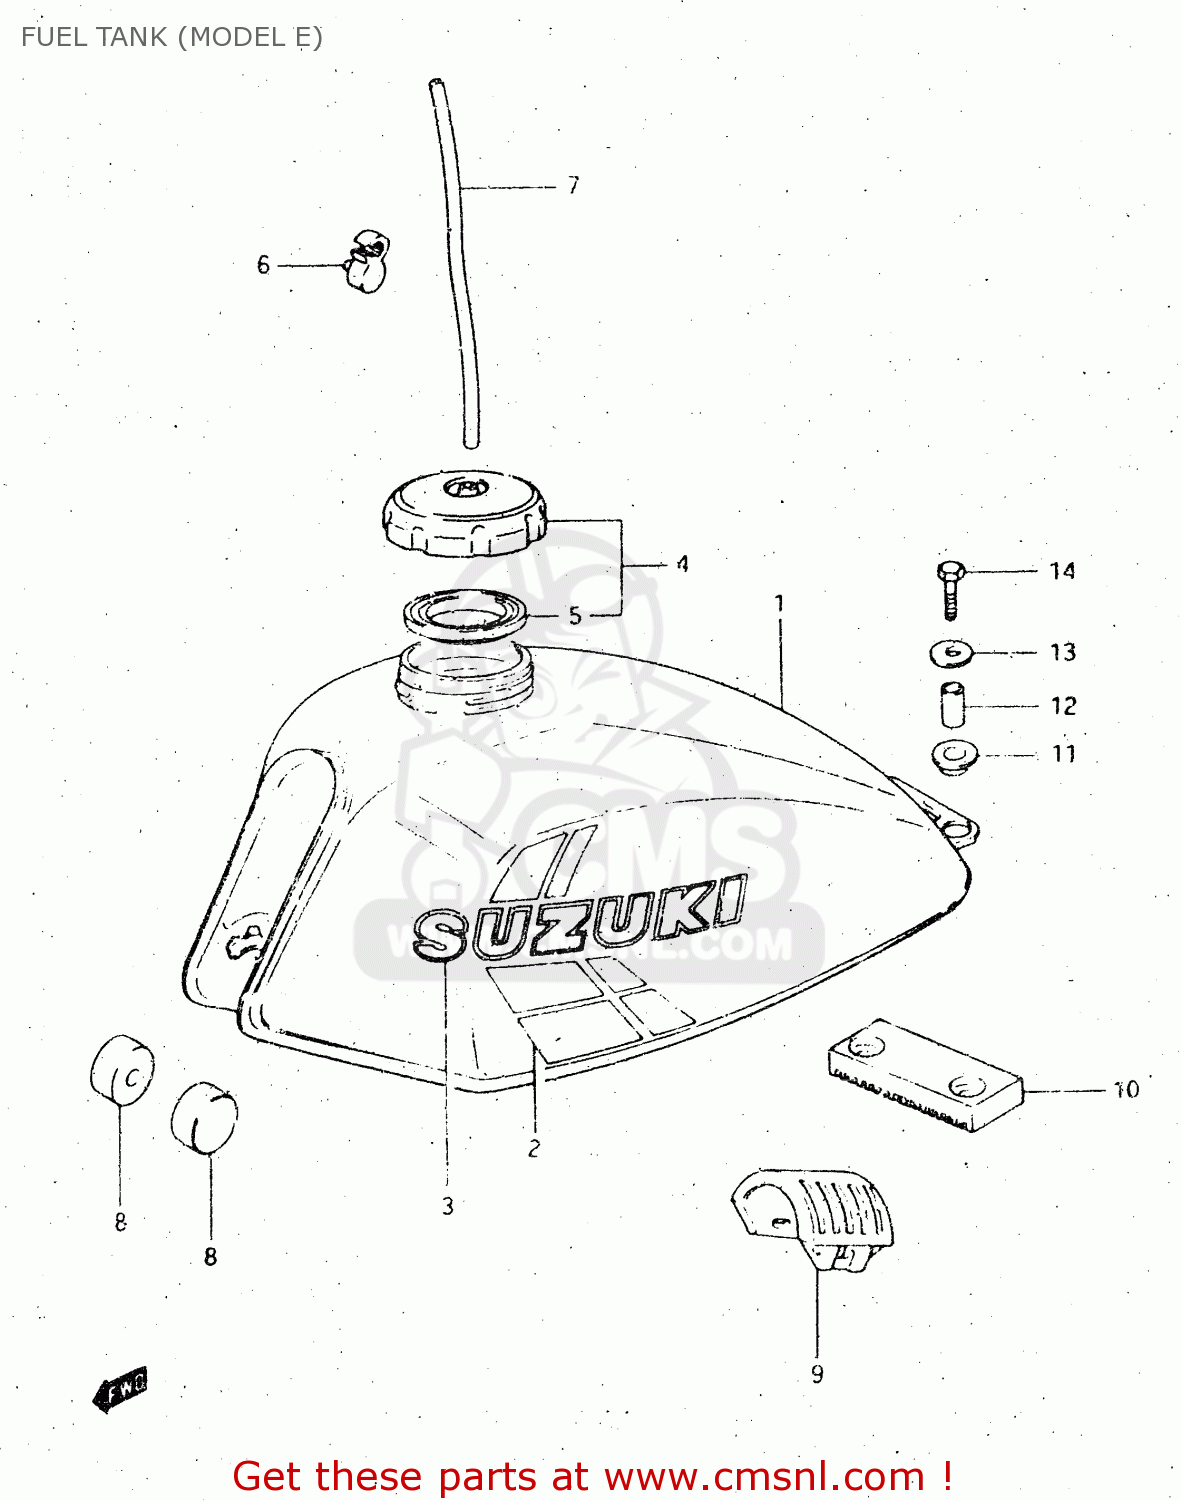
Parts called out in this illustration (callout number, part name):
1	TANK ASSY, FUEL (BLUE)
2	TAPE SET, FUEL TANK
3	EMBLEM
4	CAP,FUEL TANK
5	GASKET,FUEL TANK CAP (NAS)
6	CLAMP,FUEL TANK BREATHER HOSE
7	HOSE
8	CUSHION
9	CUSHION,FUEL TANK UPR FR
10	CUSHION,FUEL TANK,REAR
11	CUSHION
12	SPACER (6.5X10.5X29)
13	WASHER (6.5X24X1.6)
14	BOLT 6X40
